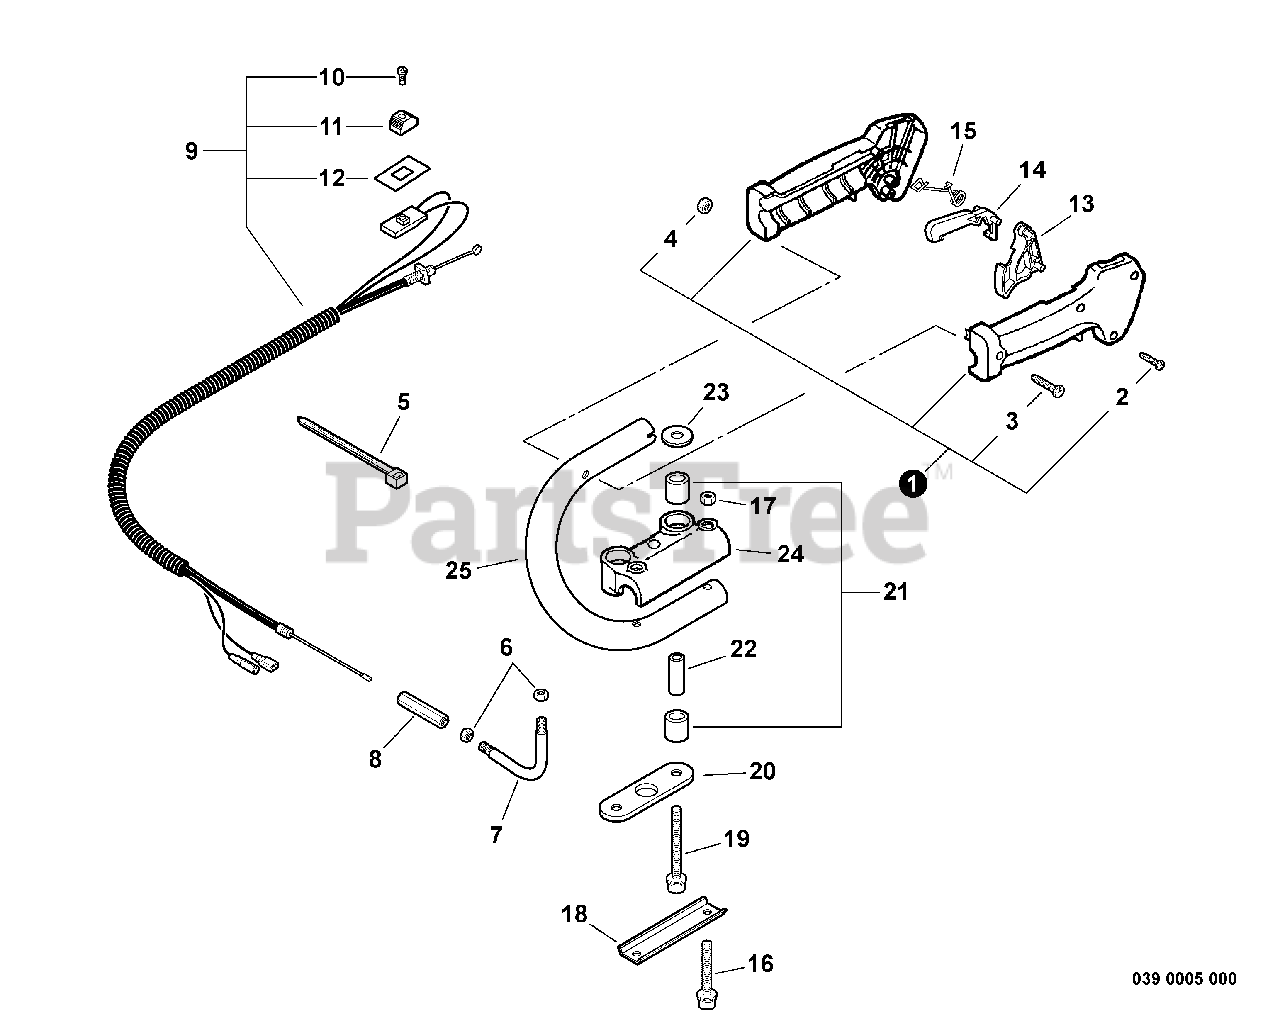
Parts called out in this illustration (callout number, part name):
1	THROTTLE CONTROL ASSY
2	SCREW - 3X25
3	SCREW - 5X30
5	TIE, CABLE - SMALL
7	TUBE, THROTTLE CABLE
8	CONNECTOR, THROTTLE CABLE
9	CONTROL CABLE ASSY
10	SCREW - 3X10
11	KNOB, SWITCH - ORANGE
12	COVER, SWITCH - STOP
13	TRIGGER, THROTTLE
14	LOCKOUT, THROTTLE
15	SPRING, LOCKOUT LEVER
16	SCREW - 5X35
18	BRACKET, HANDLE - LOWER
19	SCREW - 5X40
22	SPACER
24	BRACKET, HANDLE - UPPER
25	HANDLE - REAR
